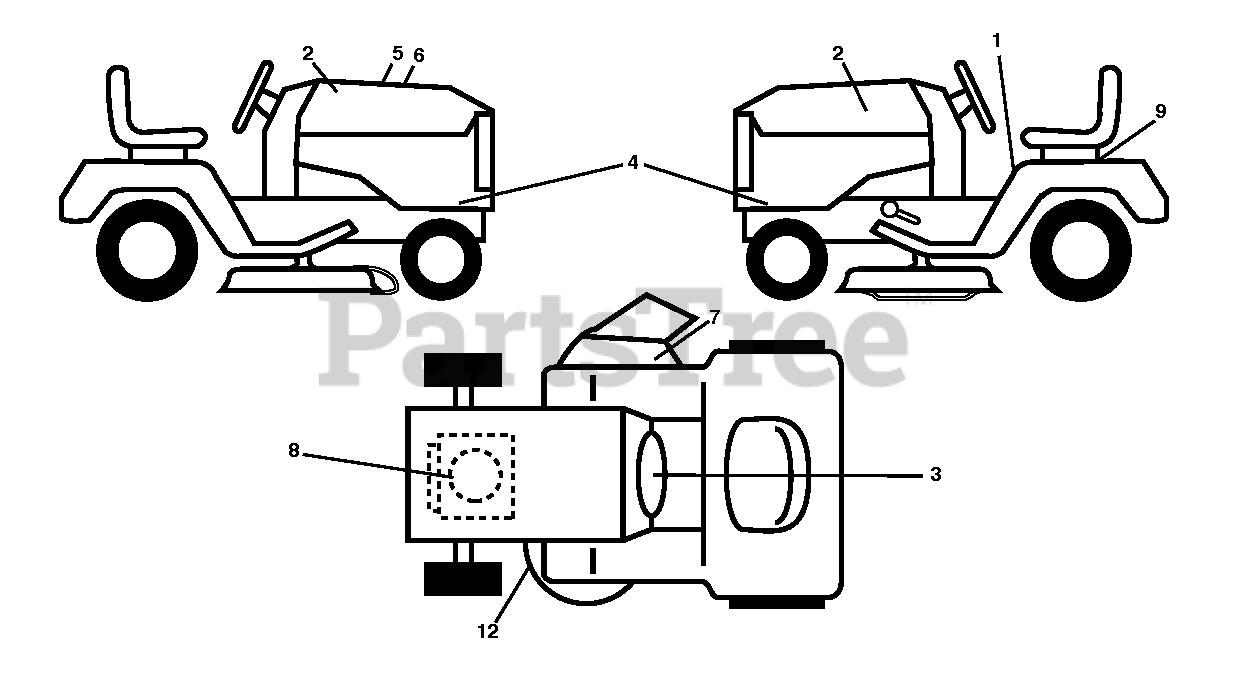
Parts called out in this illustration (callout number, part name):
1	DECAL.FENDER.WARNING.ENGLISH
2	DECAL.BADGE.170MM.TEXTLOGO.
3	DECAL, WARNING SPARK ARRESTOR
4	DECAL SIDEPANEL
5	DECAL.WARNING.CUST.RESP.E85.
6	Decal, Replacement BSM33 INTK TLW
7	DECAL, DECK DEFLECTOR, WARNING
8	DECAL.ENG.BS.18.5INTK.381713
9	DECAL BTRY SYMBOLS
12	DECAL.V-BELT.SCH.42/46"MEC/ELE
